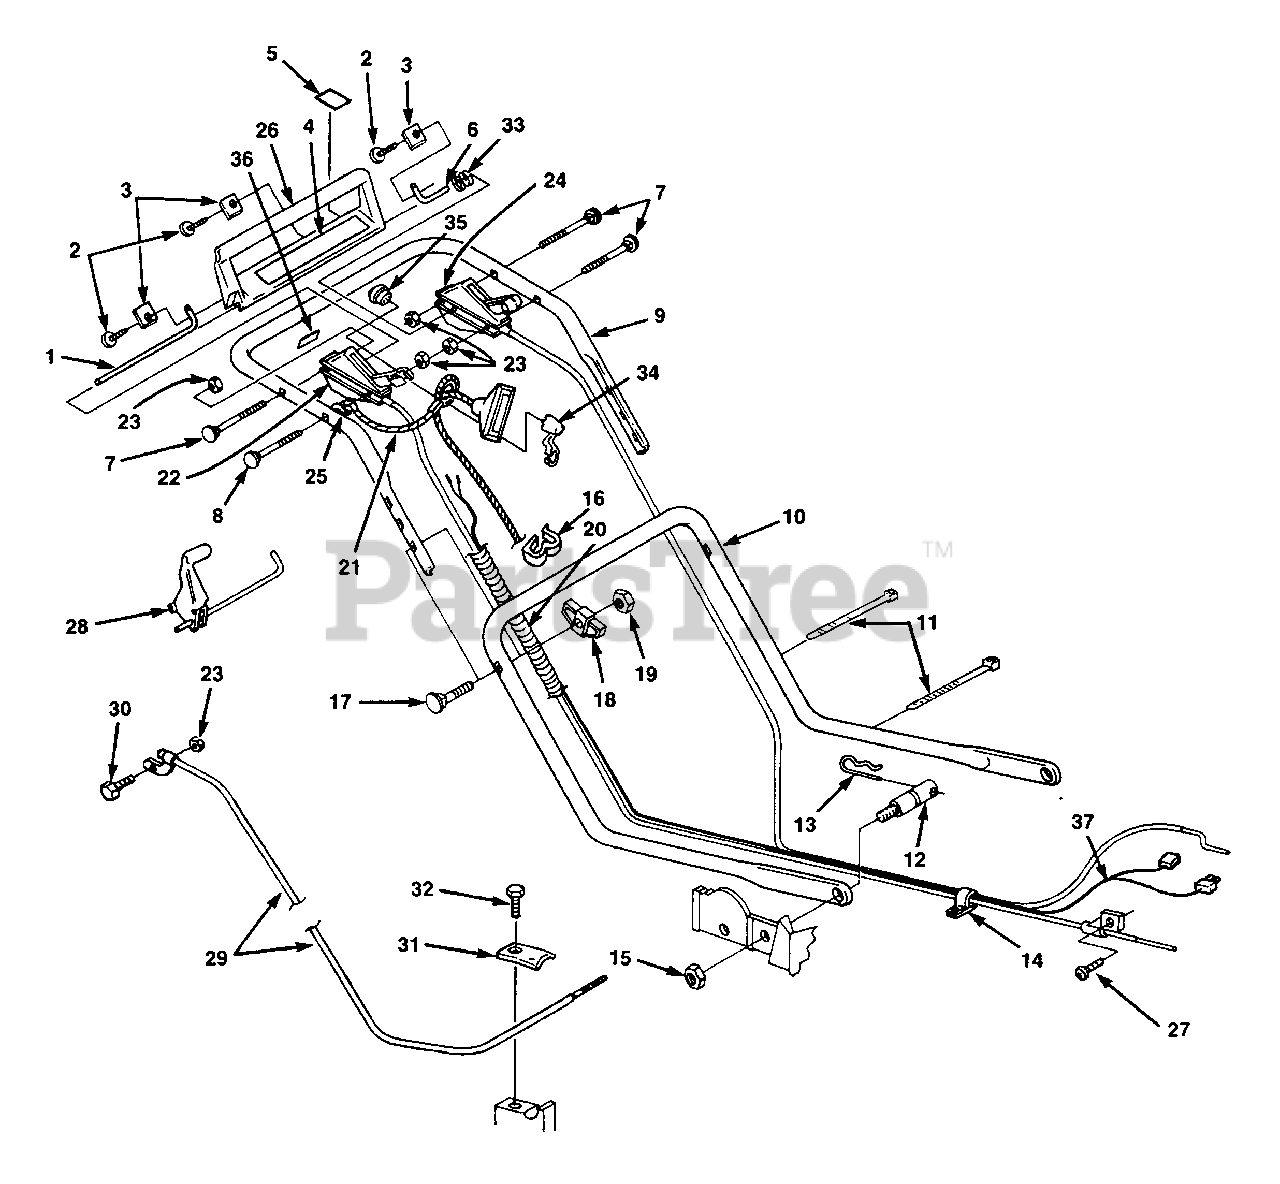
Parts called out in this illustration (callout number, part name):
1	SHAFT- Pivot
2	SCREW- Rd. hd. (1/4-10 x 5/8")
3	CLAMP- Pivot shaft
4	DECAL- Brake bail
5	DECAL- Blade Rotation
6	SHAFT- Pivot (short)
7	BOLT- Sq. neck
8	BOLT- Sq. neck
9	HANDLE Upper
10	HANDLE Lower
11	TIE- Cable
12	STUD- Handle Mtg.
13	PIN- Cotter hair
15	NUT- Hex Flange (5/16-18)
16	CLIP- Cover
17	BOLT Sq. neck
18	KNOB Handle
19	NUT- Hex (5/16-18)
20	COVER- Control cable
21	ROPE- Restraint
22	CONTROL- Manual start
23	NUT- Hex locking (1/4-20)
24	CONTROL- Throttle
25	WASHER- Curved
26	BAIL- Brake control
27	SCREW- Hex hd. (10-32 x 3/8")
28	LEVER- Traction
29	CABLE- Traction
30	SCREW- Hex hd. (1/4-20 x 1 1/2")
32	SCREW- Hx. hd.
33	SPRING- Compression
34	HOUSING- Switch
36	DECAL- Switch
37	WIRING HARNESS
